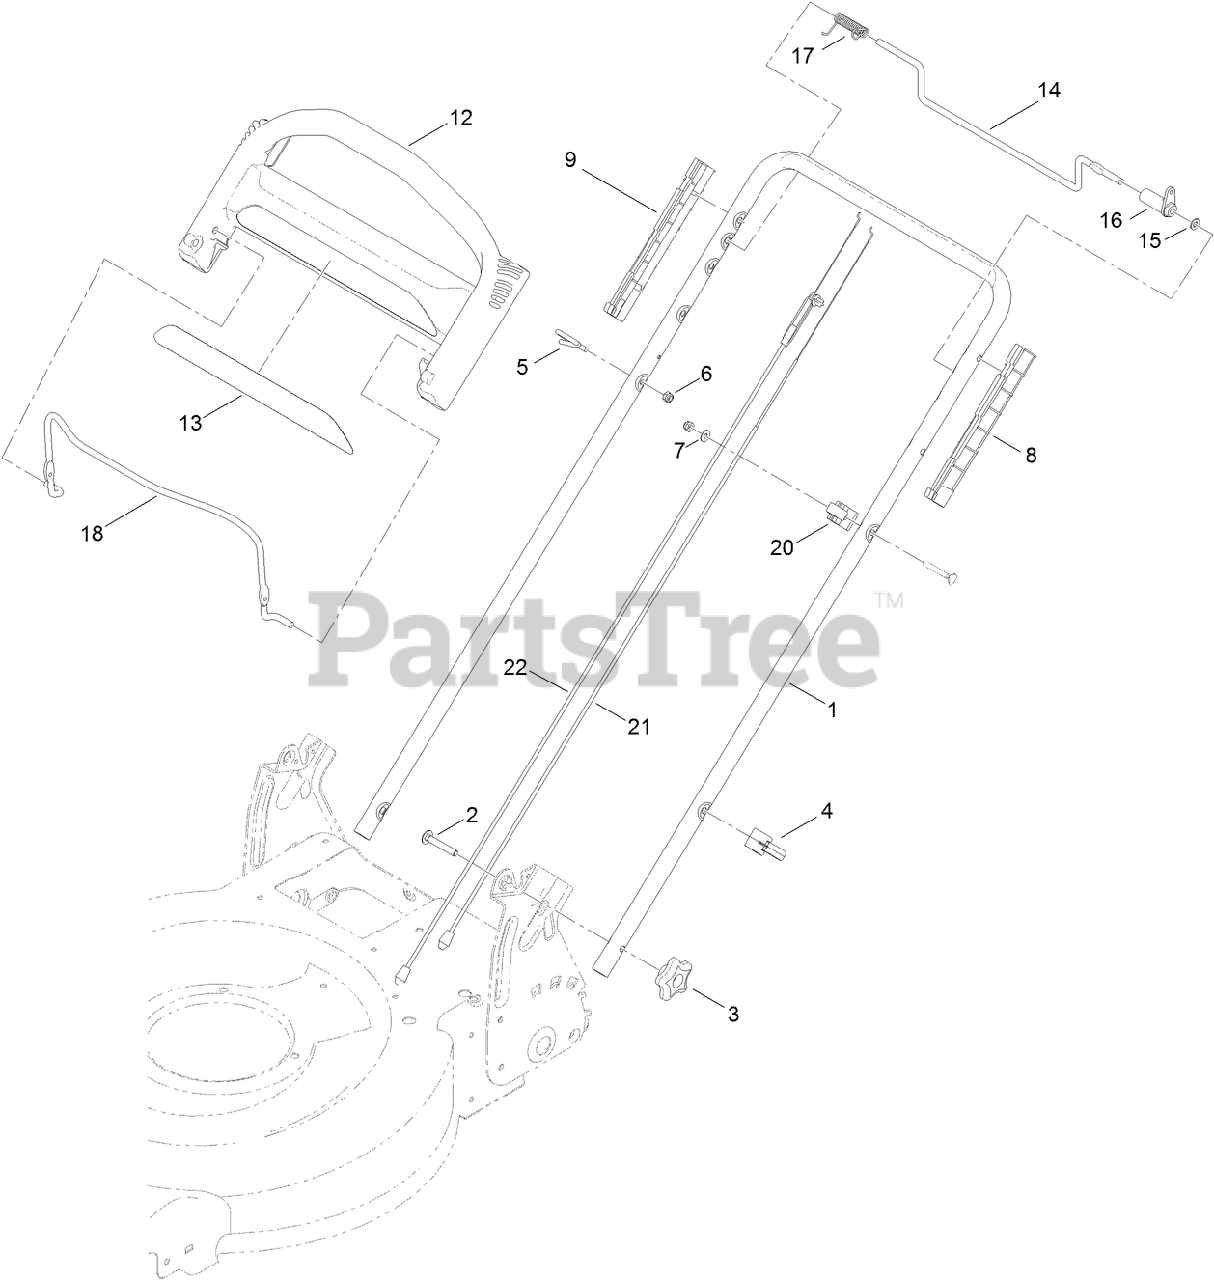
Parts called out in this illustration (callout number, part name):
2	BOLT-CARR
3	KNOB-HANDLE
4	GUIDE-CABLE
5	GUIDE-ROPE
6	NUT-LOCK, NI
7	WASHER-FLAT
8	GUIDE-LH
9	GUIDE-RH
12	HANDLE-CONTROL
15	WASHER-PLAIN
16	LEVER-TRACTION
21	CABLE-TRACTION
22	CABLE-BRAKE
